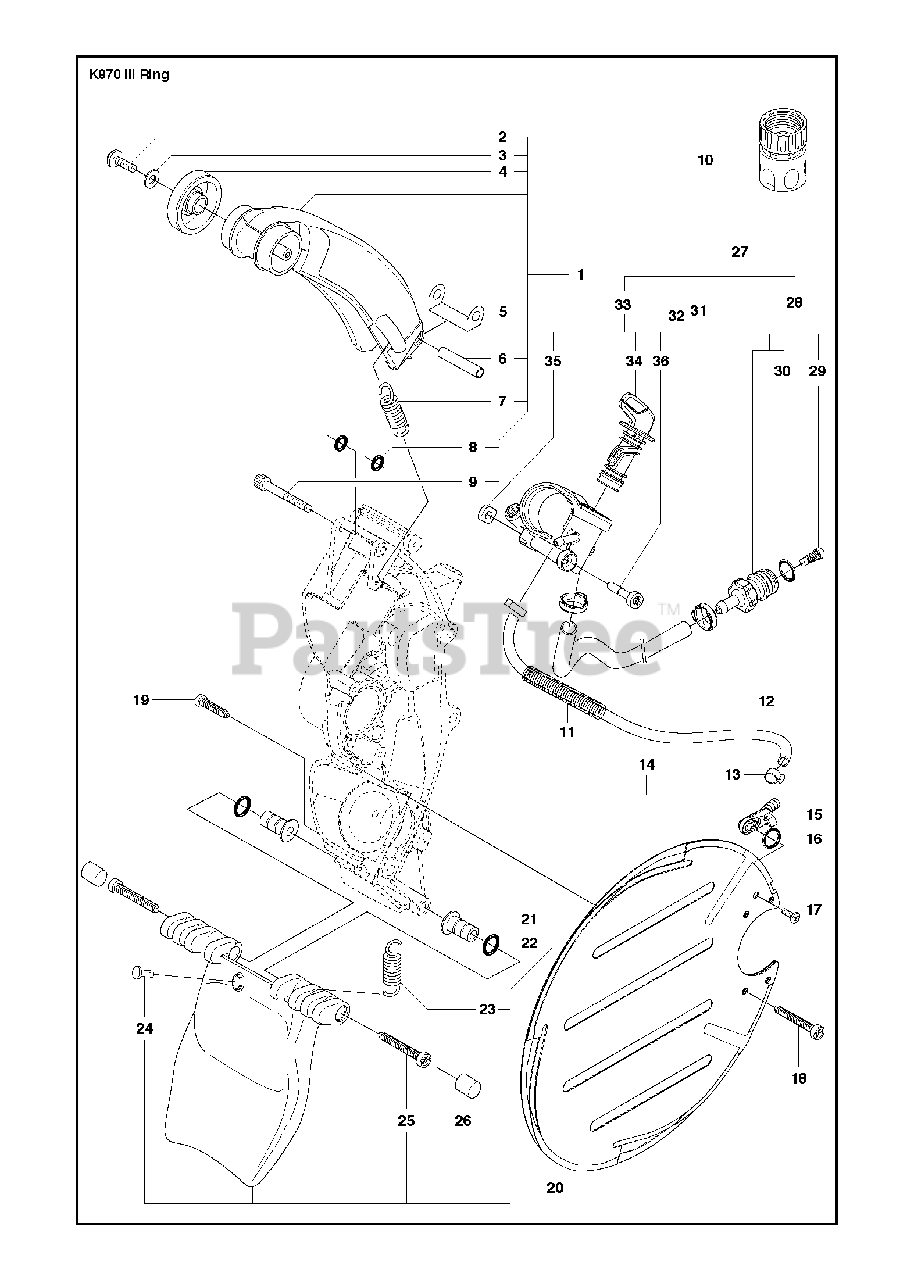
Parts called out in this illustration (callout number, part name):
1	BLADE GUARDIncl. 2 - 9
6	SPACING TUBE
9	SCREW ITXSCM
11	PROTECTIVE SPRING
13	HOSE CLAMP
17	SCREW CRPANT
19	SCREW ITXSCM
20	SPRAY GUARD ASSYIncl. 21 - 26
25	SCREW ITXSCM
27	HOSE KITIncl. 28, 31 - 33
33	VALVE ASSYIncl. 34-36
34	LEVER ASSY
36	SCREW ITXSCM
